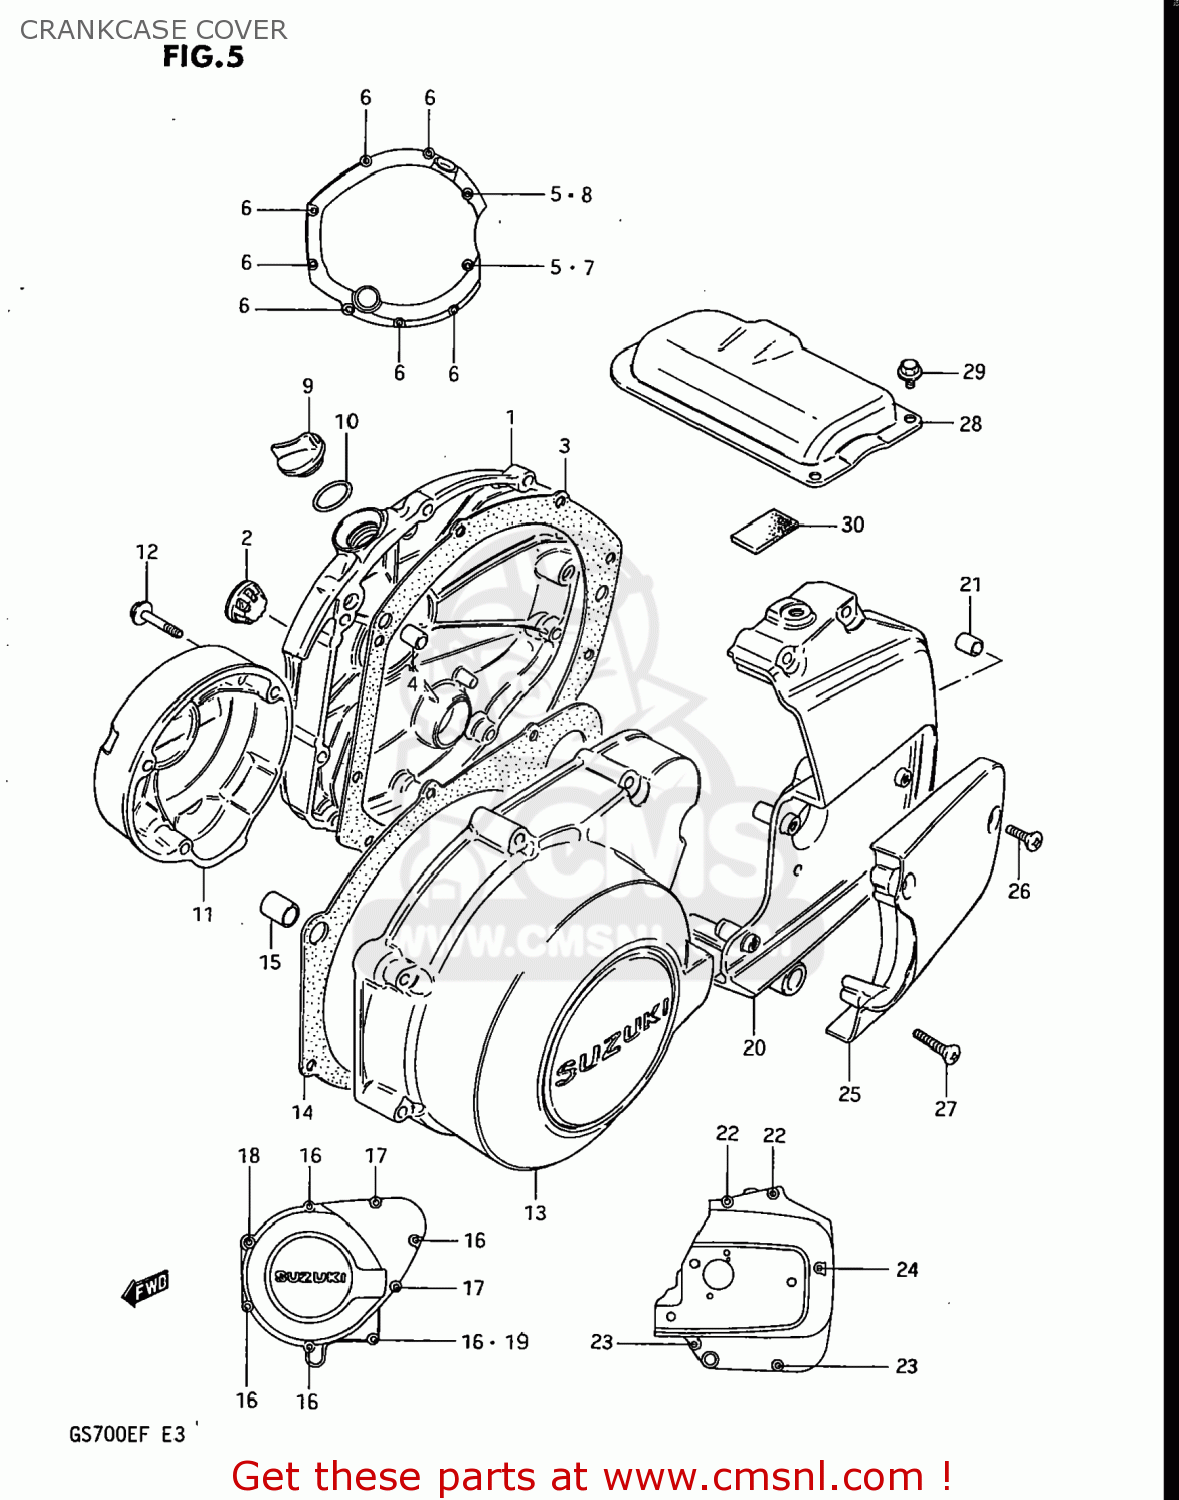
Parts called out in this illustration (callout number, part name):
1	COVER,CLUTCH
2	LENS,OIL LEVEL CHECK
3	GASKET,CLUTCH COVER (MCA)
4	PIN
5	WASHER
6	BOLT
7	BOLT
8	BOLT
9	PLUG(20X10)
10	O RING(D:3.1,ID:16.8)
11	COVER,CONTACT BRAKER
12	BOLT
13	COVER,MAGNETO
14	GASKET,MAGNETO COVER (MCA)
15	PIN (11X20)(SUS)
16	BOLT
17	BOLT
18	BOLT
19	WASHER
20	COVER,ENGINE SPROCKET
21	PIN
22	BOLT
23	BOLT
24	BOLT
25	CAP,CLUTCH RELEASE ADJUST
26	SCREW
27	SCREW
28	COVER,STARTER MOTOR
29	BOLT
30	DAMPER,STARTER MOTOR CLUTCH
